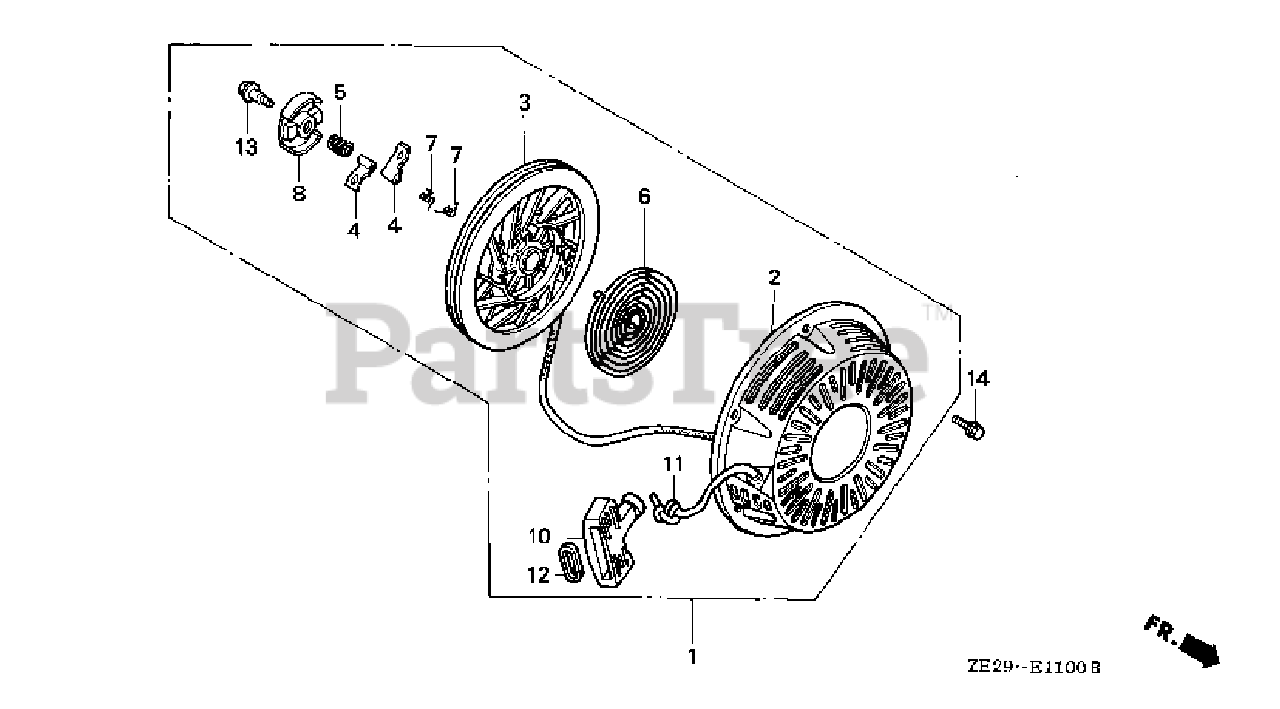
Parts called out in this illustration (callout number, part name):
1	STARTER ASSY., RECOIL *R8* (BRIGHT RED)
1	STARTER ASSY., RECOIL *NH1* (BLACK)
2	CASE, RECOIL STARTER *R8* (BRIGHT RED)
2	CASE, RECOIL STARTER *NH1* (BLACK)
3	PULLEY, RECOIL STARTER
4	RATCHET, STARTER
5	SPRING, FRICTION
6	SPRING, STARTER RETURN
7	SPRING, RATCHET
8	RETAINER, SPRING
10	GRIP, STARTER
11	ROPE, RECOIL STARTER (NA USE ALT:08550-ZG921-11)
11	ROPE, RECOIL STARTER
12	GRIP, REINFORCEMENT
13	SCREW, CENTER
14	BOLT, FLANGE (6X10)
